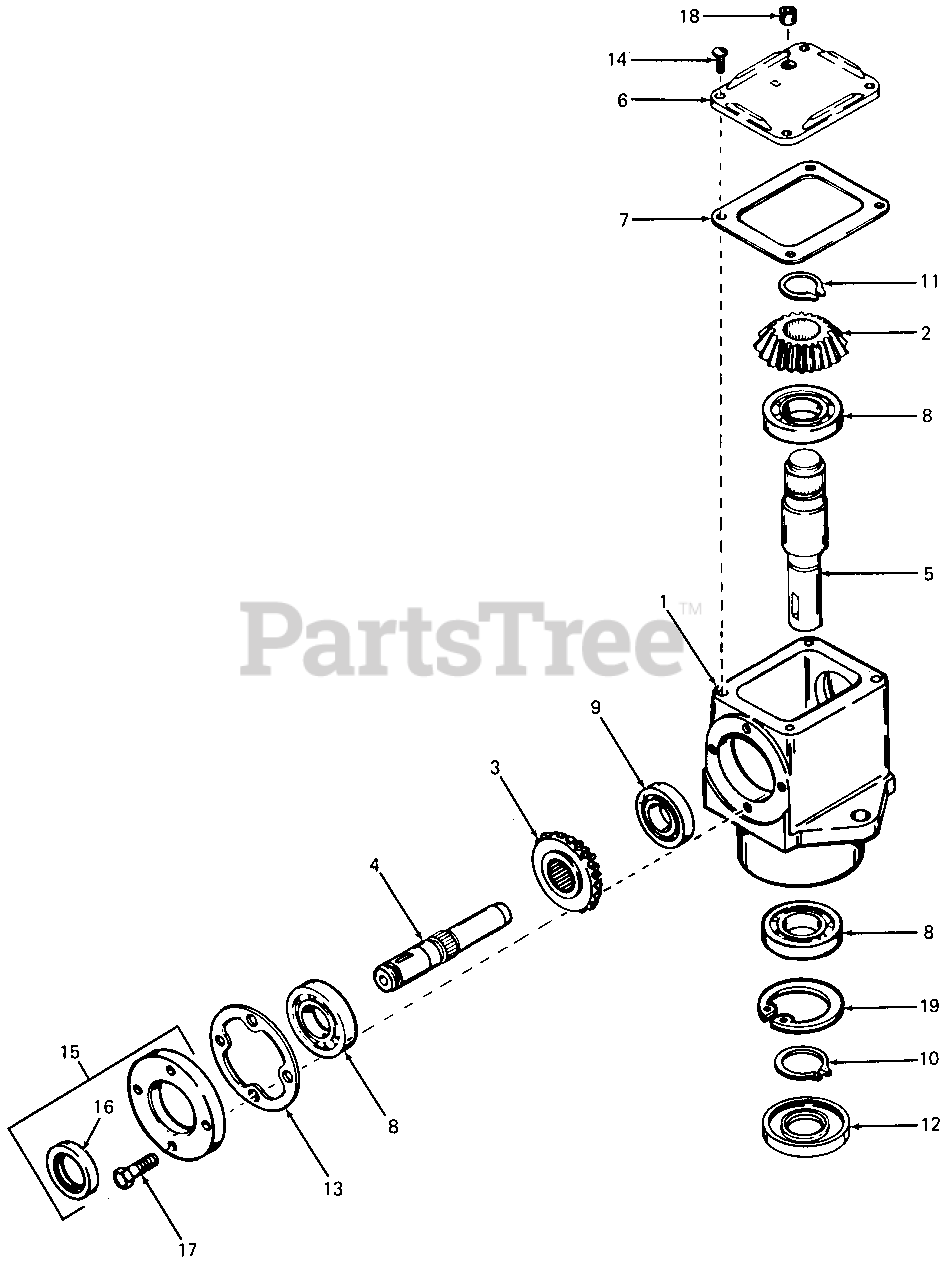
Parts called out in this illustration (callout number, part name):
1	Housing, Right Angle
2	Gear, Bevel Output
3	Gear, Bevel Input
4	Shaft, Input
5	Shaft, Output
6	Cover, Housing
7	Gasket, Cover
10	Ring, Internal Snap
11	Ring, Internal Snap
12	Seal, Output Shaft
13	Gasket, Cap
14	Screw, Pan Hd Self-Tap 10-24 X 1/2
15	Cap & Seal Assy, Retainer
16	Seal, Input Shaft
17	Screw, Hex Cap, 1/4-20 X 7/8
18	Plug, Pipe, Hex Countersunk, 1/8-27
19	Ring, External Snap
